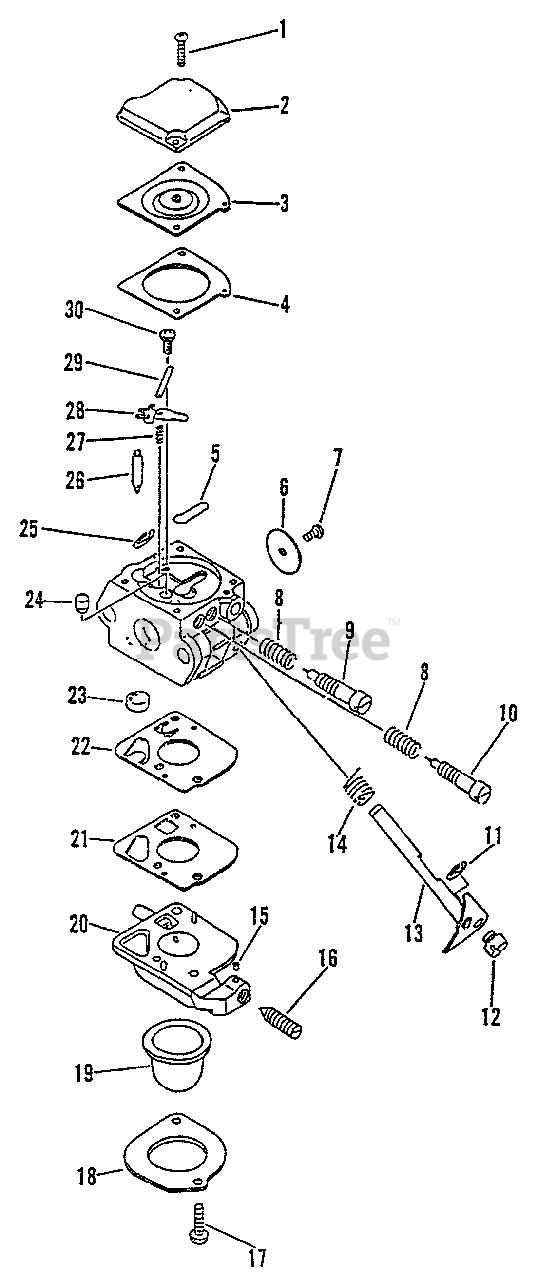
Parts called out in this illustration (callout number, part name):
2	COVER, DIAPHRAGM
3	DIAPHRAGM
4	GASKET, DIAPHRAGM
5	PLUG, WELCH
6	VALVE, THROTTLE
7	SCREW 3×4.5
8	SPRING, NEEDLE
9	NEEDLE, HIGH SPEED
10	NEEDLE, IDLE
13	SHAFT, THROTTLE
14	SPRING, THROTTLE RETURN
15	PIECE, FRICTION
16	SCREW, IDLE ADJUST
18	RETAINER
19	BULB, PURGE
20	BODY ASSY, PURGE
21	GASKET, PUMP
22	DIAPHRAGM, PUMP
23	STRAINER
24	NOZZLE, CHECK VALVE
26	VALVE, NEEDLE
27	SPRING
28	LEVER, METERING
29	PIN, METERING LEVER
